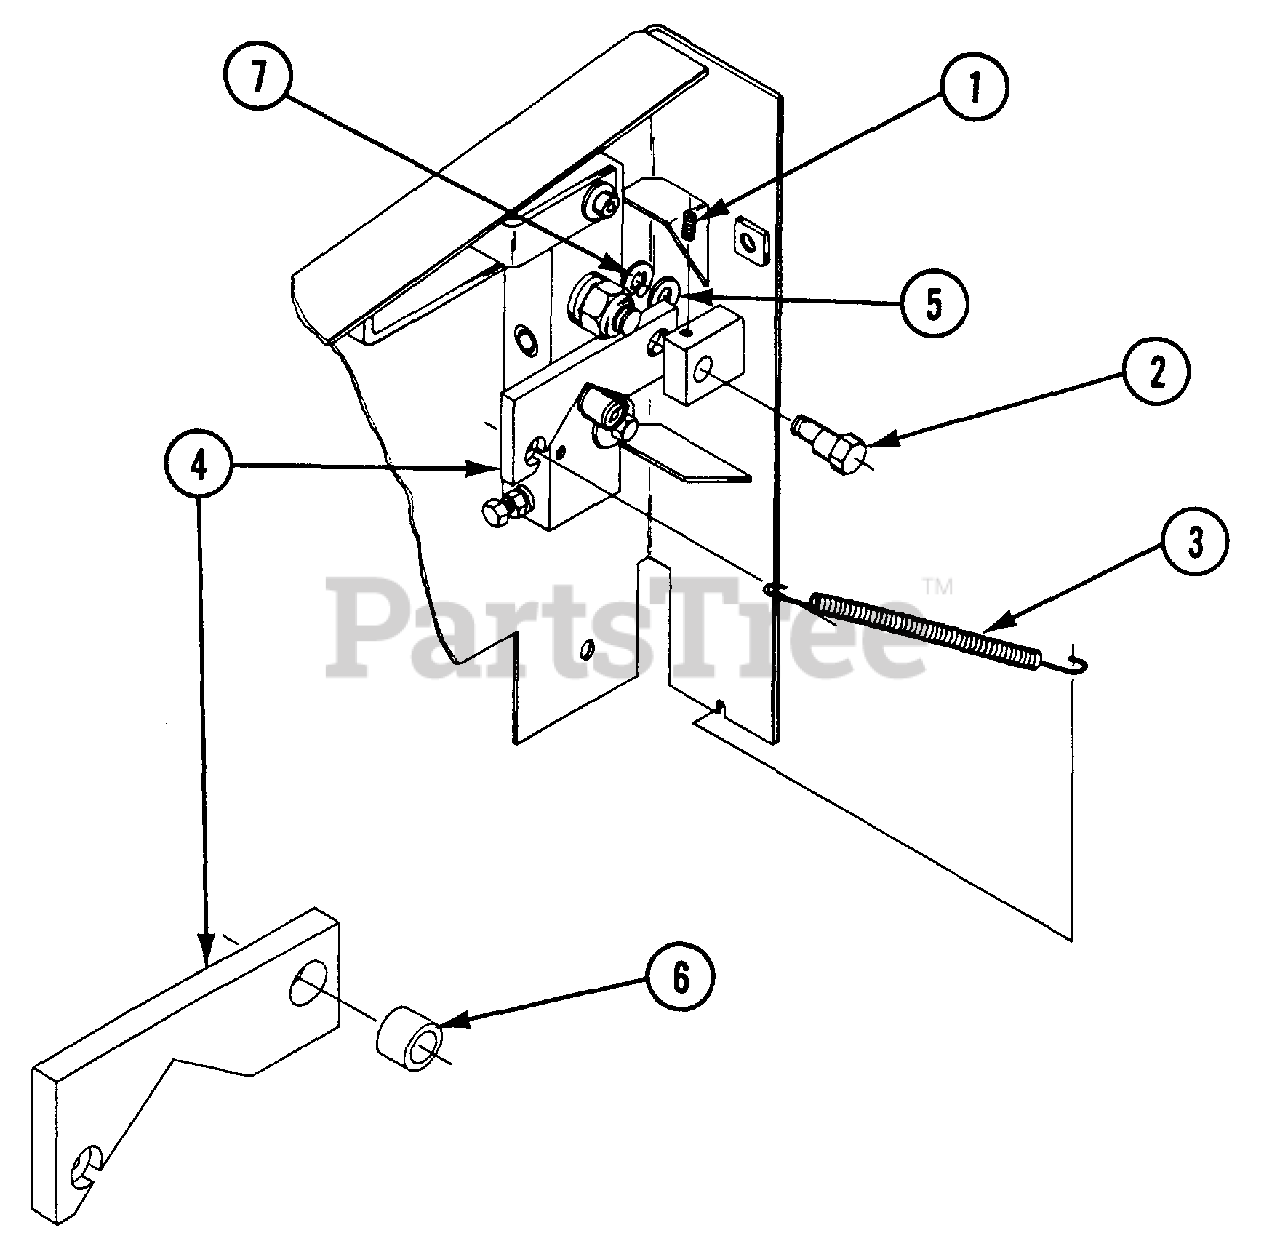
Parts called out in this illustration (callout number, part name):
1	SETSCREW, SKTHD, 1/4-20 X 5/16 NYLOC
2	CENTERING CAM, ECCENTRIC
3	EXTENSION SPRINGER 3/8 OD X 5-5/8"
4	CENTERING CAN BAR, RIGHT
4	CENTERING CAM BAR, LEFT
5	THRUST WASHER
6	CAM BUSHING
7	E-RING
